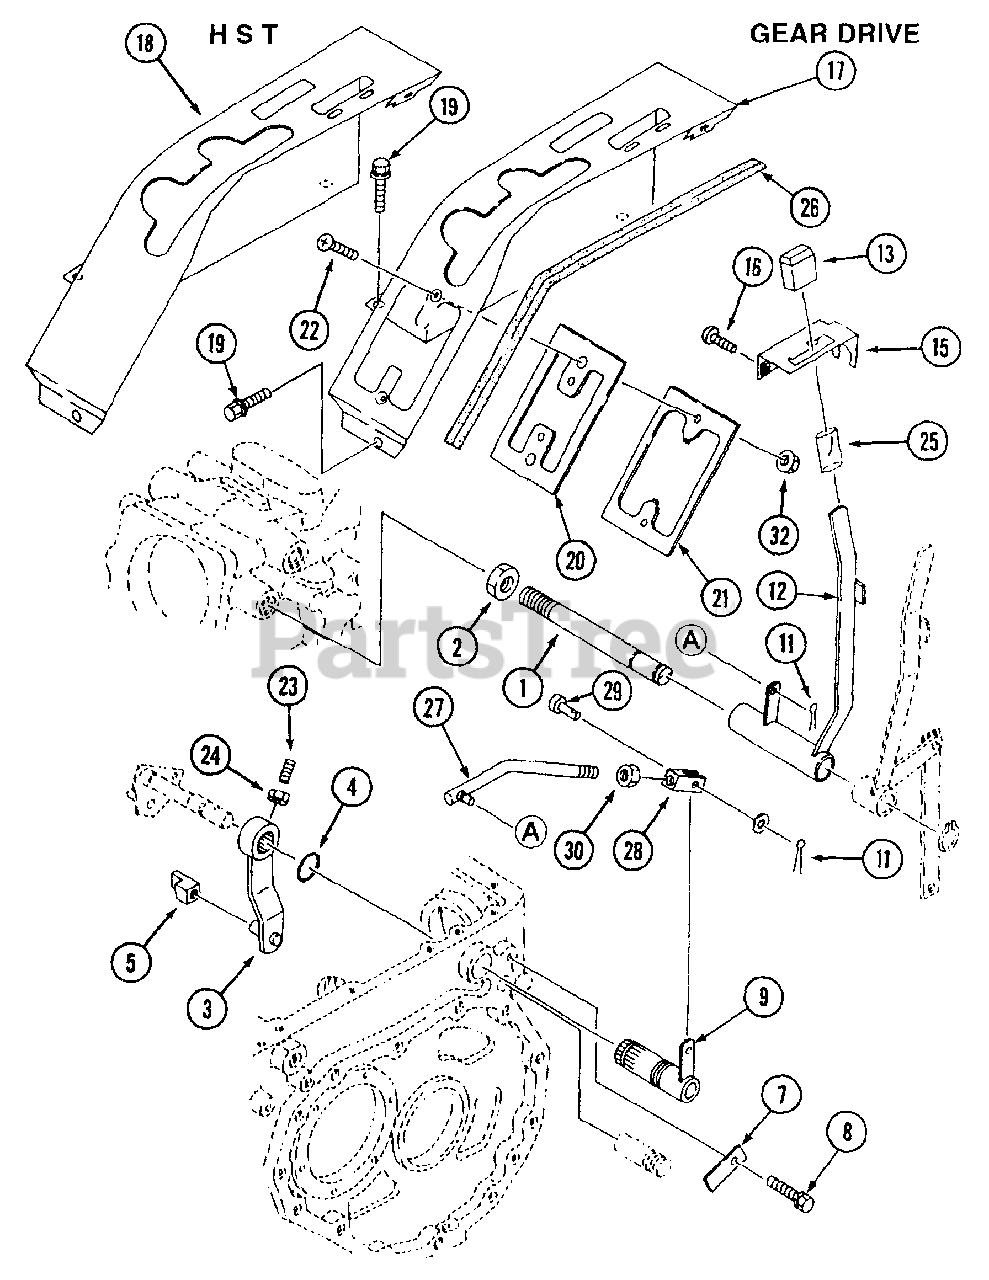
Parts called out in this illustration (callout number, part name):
1	Shaft, PTO Lever
3	Shifter, R. PTO
9	Arm, Rear PTO
11	Pin, Split
12	Lever, Rear PTO
15	Plate, Rear PTO
17	Lever, Guide L.H.
18	Lever, Guide L.H.
20	Guide, Rubber
21	Plate
22	Screw
32	Nut
